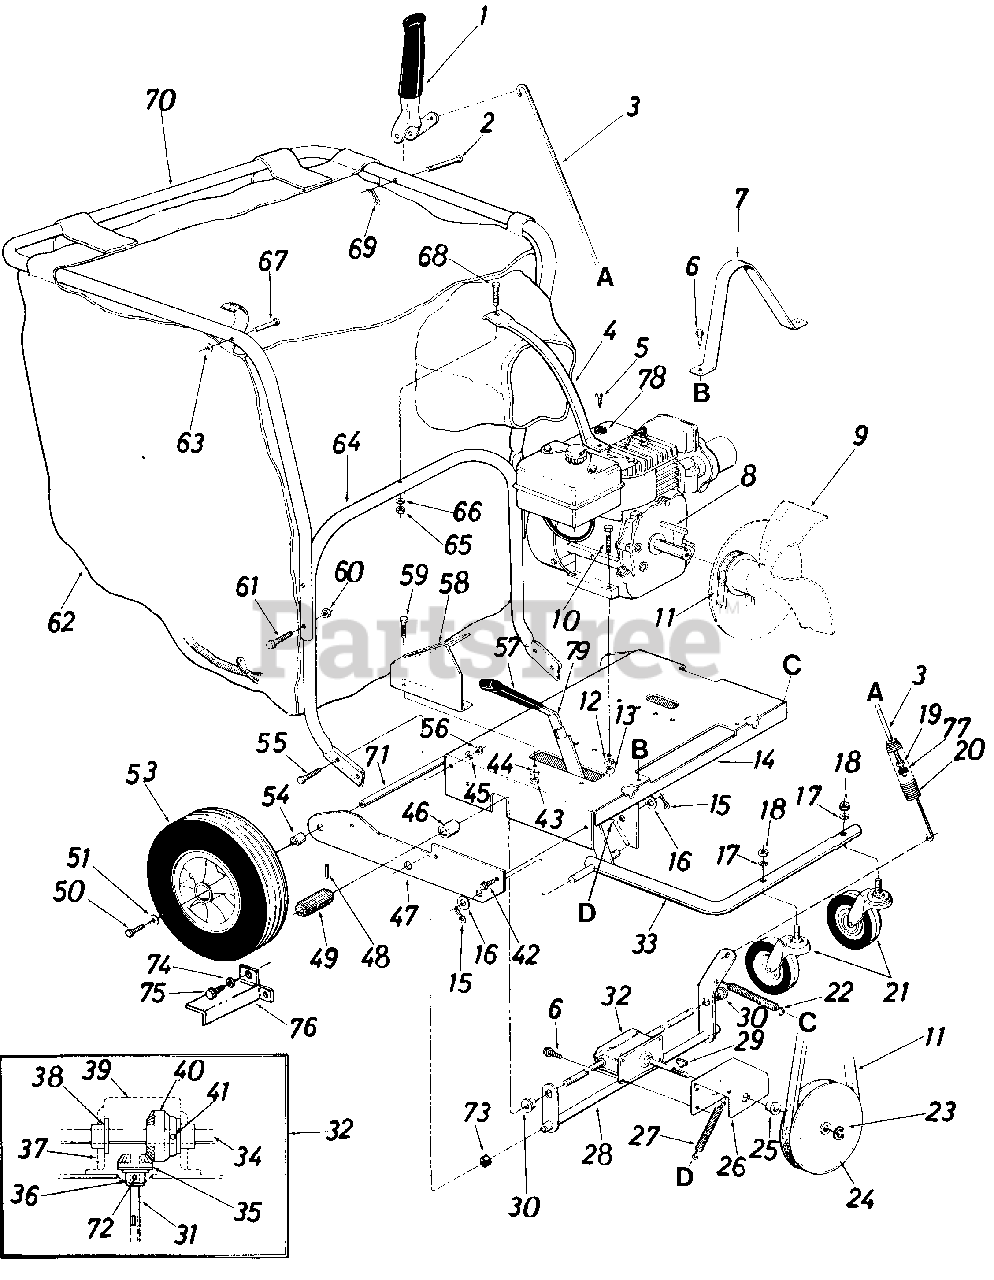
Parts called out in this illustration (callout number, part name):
1	Clutch Grip Ass'y.
2	Clevis Pin .375" Dia. x 1.88" Lg.
3	Clutch Rod 32" Lg.
4	Handle Brace
5	Part of Engine
6	Hex Wash. Hd. AB Tap Scr. 1/4" x .62" Lg.
9	Air Vane Plate Ass'y.
10	Hex Bolt 5/16-18 x 1.50"*
11	"V"-Belt 1/2" x 26" Lg.
12	L.-Wash. 5/16" I.D.*
13	Hex Nut 5/16-18 Thd.*
14	Engine Mounting Frame Ass'y.
15	Cotter Pin 5/32" Dia. x 1.25"*
16	Fl.-Wash. .63" I.D. x 1.25" O.D.
17	L.-Wash. 1/2" I.D.*
18	Hex Nut 1/2-13 Thd. *
19	Hex Cent. L.-Nut 1/4-20 Thd.
20	Extension Spring .78" O.D. x .750" Lg.
21	Swivel Caster Wheel 5" Dia. x 1.25"
22	Extension Spring .38" O.D. x 7.50" Lg.
23	Snap "E"-Ring .50" Dia. Shaft
24	"V"-Pulley 5/8" x 6.50" O.D.
25	Flange Bearing .502" I.D.
28	Clutch Bracket Ass'y.
29	#2 Woodruff Key 3/32" Dia. x .81" Lg.
30	Hex Flange Bearing Bronze .625" I.D.
31	Pinion Shaft .50" Dia. x 5.0"
32	Gear Box Ass'y. Comp.
33	Caster Arm Ass'y.
34	Drive Shaft .624" Dia. x 22.75" Lg.
35	Bevel Gear. 50" I.D. x 14 Teeth
36	Flange Bearing .503" I.D.
37	Gear Box
38	Flange Bearing .630" I.D.
39	Gear Box Cover
40	Bevel Gear .62" I.D. x 28 Teeth
41	Spring Pin Spiral 3/ 16" Dia. x 1.25" Lg.
42	Hex Wash. Hd. "AB" Tap Scr. 5/16" x.75" Lg.
43	Hex Nut 5/16-18 Thd.*
44	L.-Wash. 5/16" I.D.*
45	L.-Wash. 5/16" I.D.*
46	Spacer .63 I.D. x .88" O.D. x .56" Lg.
49	Drive Pinion
50	Hex Locking Bolt 5/16-24 x.62" Lg.
51	Fl.-Wash. .34" I.D. x 87" O.D.
53	Wheel Ass'y.-Comp. 12" x 3" (Incl. Ball Bearings)
54	Spacer .63" I.D. x 1.00" O.D. x .94" Lg.
55	Hex Bolt 5/16-18 x .75" Lg.
56	Hex Nut 5/16-18 Thd.*
57	Flat Grip Vinyl
58	Index Plate
59	Hex Bolt 5/16-18 x .75" Lg.*
60	Hex Cent. L.-Nut 1/4-2 Thd.
61	Hex Bolt 1/4-20 x 1.75" Lg.
62	Vacuum Bag-Felt
63	Push Speed Nut .25" Dia. Stud
64	Lower Handle
65	Hex Nut 1/4-20 Thd.*
66	L.-Wash. 1/4" I.D.*
67	Stud Pin .250" Dia. x 1.75"
68	Hex Bolt 1/4-20 x 1.75" Lg.*
69	Internal Cotter Pin 3/8" Dia.
70	Upper Handle
71	Rear Axle .624" Dia. x 24.37"
72	Spring Roll Pin 5/32" Dia. x 1.12
73	Spacer.82" I.D. x 1.00" O.D. x .305 Lg.
74	L.-Wash. .265" I.D.
75	Hex Self Tap Scr. 1/4" x 3/8" Lg.
78	Belleville Washer
79	Height Adj. Handle
